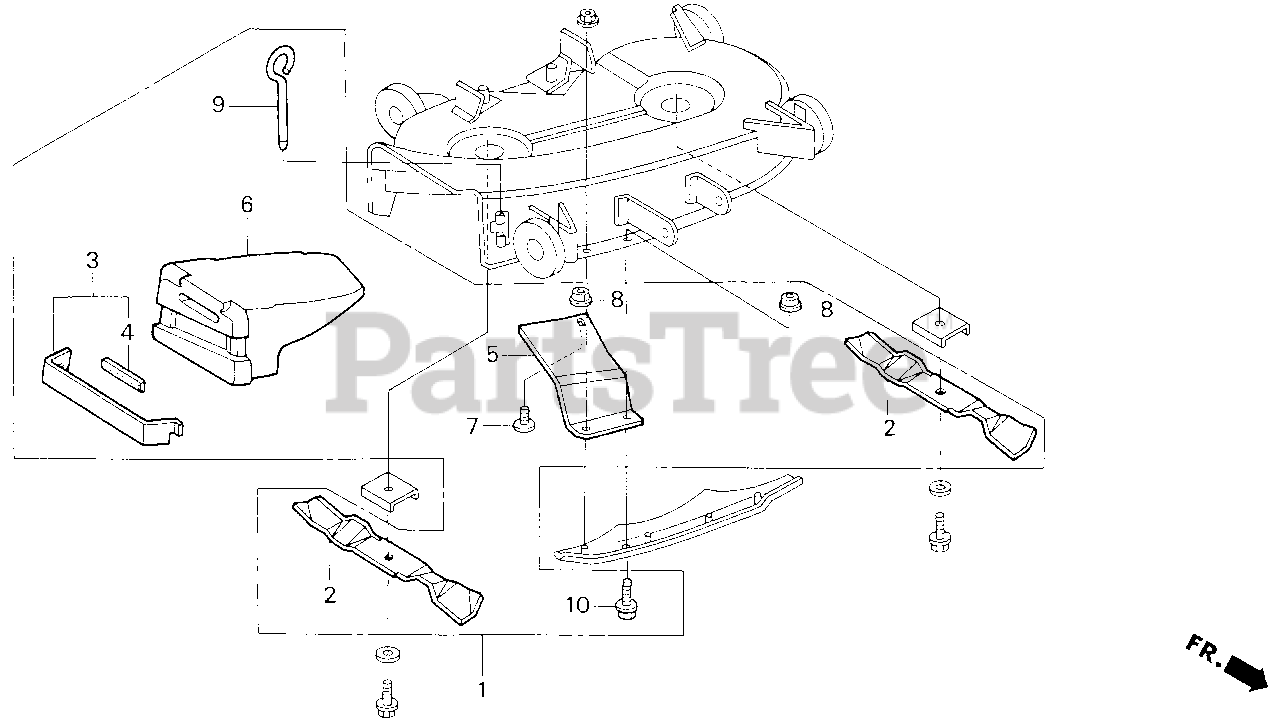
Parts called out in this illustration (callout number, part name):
1	MULCHING KIT (38")
2	BLADE, ROTARY
3	COVER, SWIRL GUIDE
4	SEAL, SWIRL GUIDE COVER
5	GUIDE A, SWIRL
6	GUIDE B, SWIRL
7	BOLT, SPECIAL (9X15)
8	NUT, FLANGE (8MM)
10	BOLT, FLANGE (8X22)
